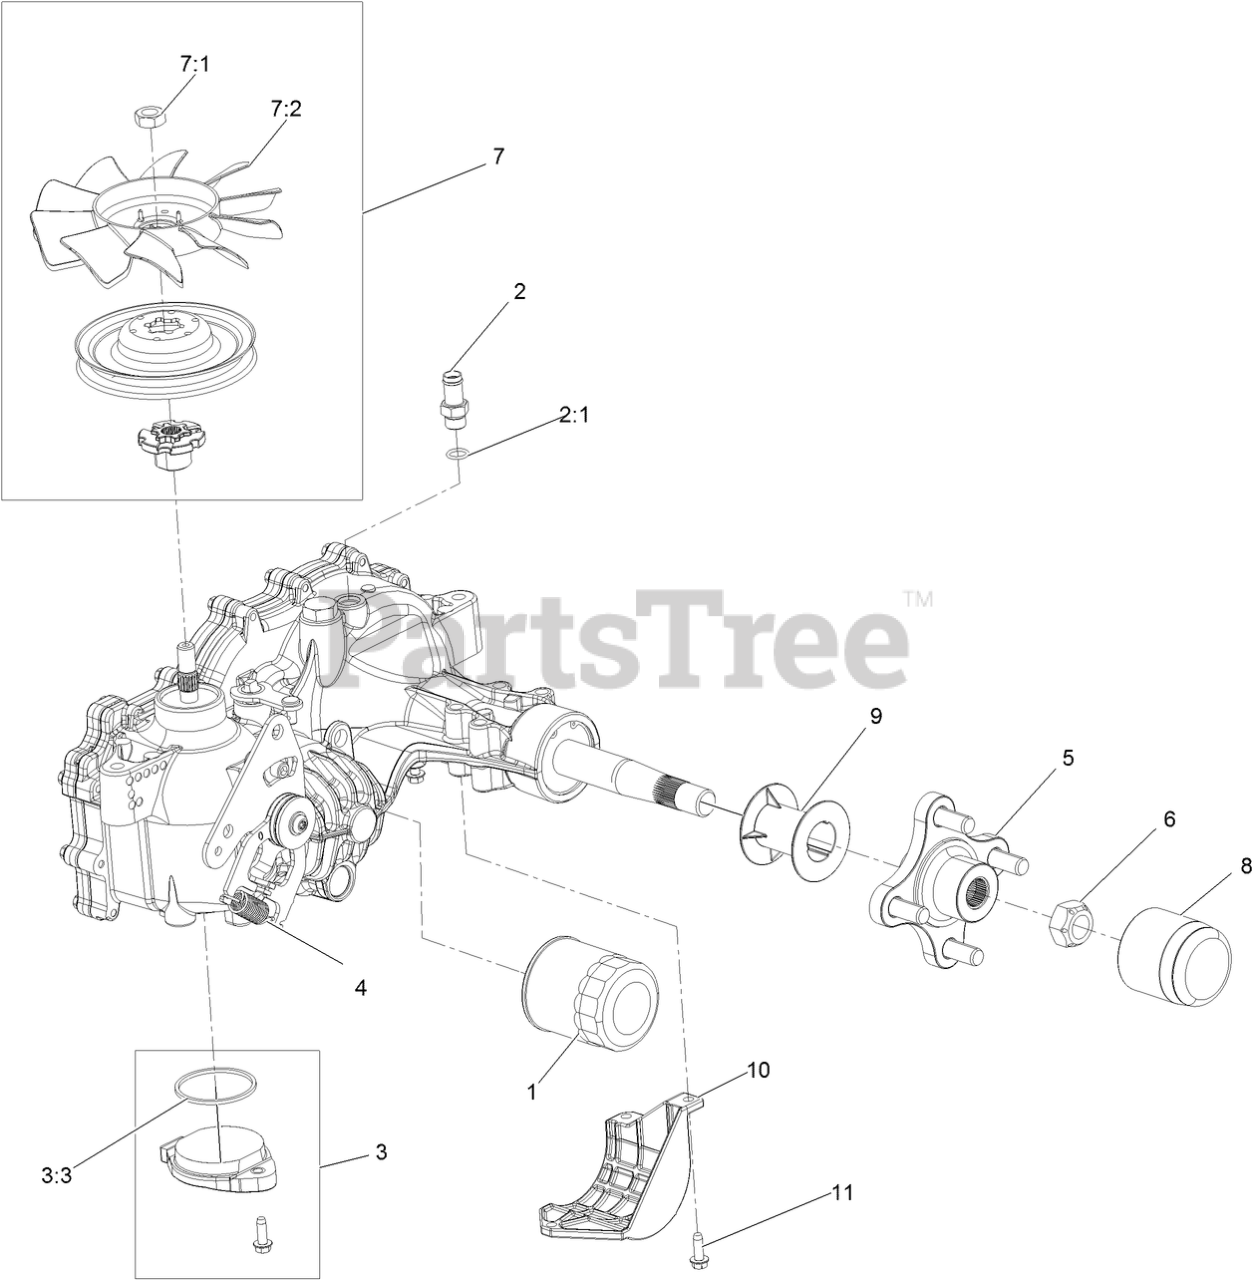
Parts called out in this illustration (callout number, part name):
1	ELEMENT-OIL FILTER, HYD
2	ADAPTER-STRAIGHT
2:1	O-RING
3	CHARGE KIT
3:3	O RING-SEAL
4	SPRING-EXTENSION
5	HUB-OFFSET
6	NUT-HUB
7	FAN AND PULLEY KIT
7:1	NUT-HJ
8	CAP-AXLE, LONG
9	TUBE-AXLE
10	GUARD-FILTER, LH
99	BRAKE SHAFT SEAL KIT
